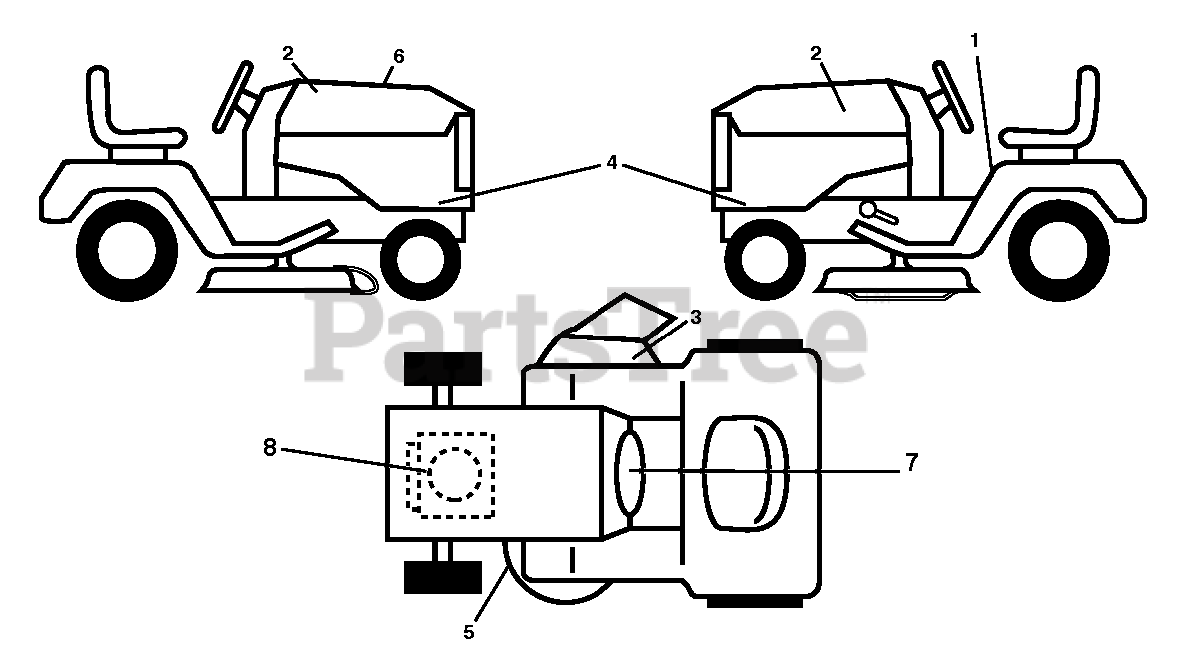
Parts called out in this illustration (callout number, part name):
1	DECAL.WARNING.2007.ENG/FR
2	DECAL.WB.178MM.15.HUSQ.NEWBRAN
2	DECALS.WARN.CA.SPKARREST/PROP
3	DECAL, DECK DEFLECTOR, WARNING
4	DECAL TRACTOR SIDE PANEL DECAL
5	DECAL.V-BELT.SCH.42/46"MEC/ELE
7	DECALS.WARN.CA.SPKARREST/PROP
8	DECAL.ENG.BS.18.5INTK.381713
